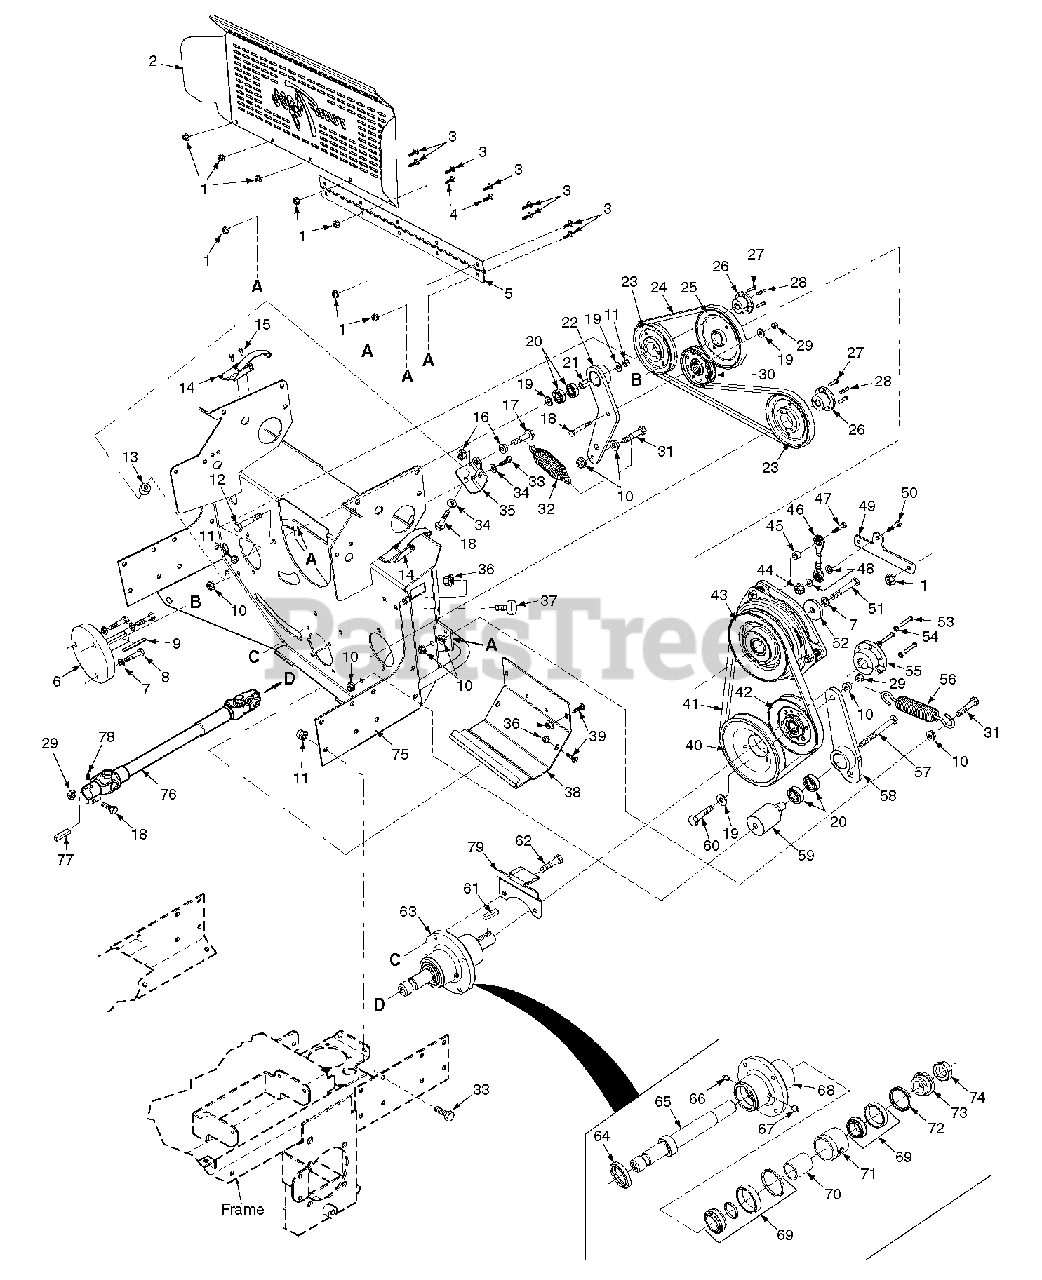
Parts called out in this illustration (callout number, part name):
1	Nut, Serrated Flange 1/4-20
2	Belt Guard, Rear
3	Bolt, Carriage 1/4-20 x 1/2"
4	Bolt, Carriage 1/4-20 x 3/4"
5	Hinge, Belt Guard
6	Stub Shaft, (Kubota)
7	Lockwasher, 7/16" Spring
8	Bolt, Hex Head M10 x 1.5 x 35
9	Key, 1/4 x 1/4 x 3-1/4"
10	Nut, Serrated Flange 3/8-16
11	Nut, Elastic Stop 3/8-16
12	Bolt, Hex Head 3/8-16 x 1-3/4" Grd 8
13	Spacer
14	Latch, Hood
15	Screw, #10-32 x .56
16	Nut, Serrated Flange 1/2-13
17	Bolt, Hex Head 1/2-13 x 2" Grd 8
18	Bolt, Hex Head 3/8-16 x 1-3/4"
19	Washer, 3/8" Hardened
20	Ball Bearing
21	Spacer, Idler Bearing
22	Idler Arm Weldment, Pump Drive
23	Pulley, 6.35" O.D.
24	Belt, Pump Drive - Kubota
25	Pulley, 4.55 Dia. - 1.125 Bore - Kubota
26	Tapered Hub, 17mm Bore
27	Bolt, Hex Head 1/4-20 x 1" Grd 8
28	Key, 5 x 5 x 35 mm
29	Nut, Center Lock 3/8-16
30	Pulley, Idler 4" Dia.
31	Bolt, Hex Head 3/8-16 x 1-1/2" Grd 8
32	Spring, Transmission Idler
33	Bolt, Hex Head 3/8-16 x 1"
34	Flatwasher, 3/8-.391 x .938 x .105
35	Bracket
36	Nut, Serrated Flange 5/16-18
37	Bumper, Rubber
38	Cover, Rear
39	Bolt, Carriage 5/16-18 x 3/4"
40	Pulley, 6.70" O.D. Tapered Bore
41	Belt, Deck Drive
42	Pulley, Idler 5" Dia.
43	Clutch, Ogura GT 3.5 - 1.125 Bore
44	Nut, Hex Elastic Stop 5/16-18
45	Spacer
46	Rod Assembly, Clutch Anti-Rotation
47	Bolt, Hex Head 5/16-18 x 1-1/2"
48	Flatwasher, 5/16"
49	Bracket, Anchor, Anti-Rotation
50	Bolt, Hex Head 5/16-18 x 1-1/4"
51	Bolt, Hex Head 7/16-20 x 2-1/4"
52	Flatwasher, 7/16-.469 x 1.75 x .25
53	Bolt, Hex Head 1/4-20 x 1-3/8"
54	Lockwasher, 1/4" Spring
55	Tapered Hub, 1" Bore
56	Spring, PTO
57	Bolt, Hex Head 3/8-16 x 4-1/2" Grd 8
58	Idler Arm Weldment, PTO Drive
59	Pivot, Idler PTO
60	Bolt, Hex Head 3/8-16 x 2-1/2" Grd 8
61	Key, 1/4 x 1/4 x 1-1/2"
62	Bolt, Hex Head 5/16-18 x 1-3/4" Grd 8
63	Spindle Assembly, Deck Drive
64	Seal, 2.0 OD x 1.5 Bore
65	Shaft, Deck Drive
66	Grease Fitting, 1/4-28
67	Relief Fitting
68	Spindle Housing
69	Roller Bearing Tapered
70	Spacer, Inside
71	Spacer, Outside
72	Seal, 2.0 OD x 1.625 Bore
73	Spindle Bushing, Bottom
74	Nut, 1.06-18 Thread
75	Pump Mounting Plate Weldment
76	Driveshaft
77	Key, 1/4 x 1/4 x 1"
78	Set Screw, 3/8-16 x 3/4" Torx Socket
79	Bracket, Belt Guide
